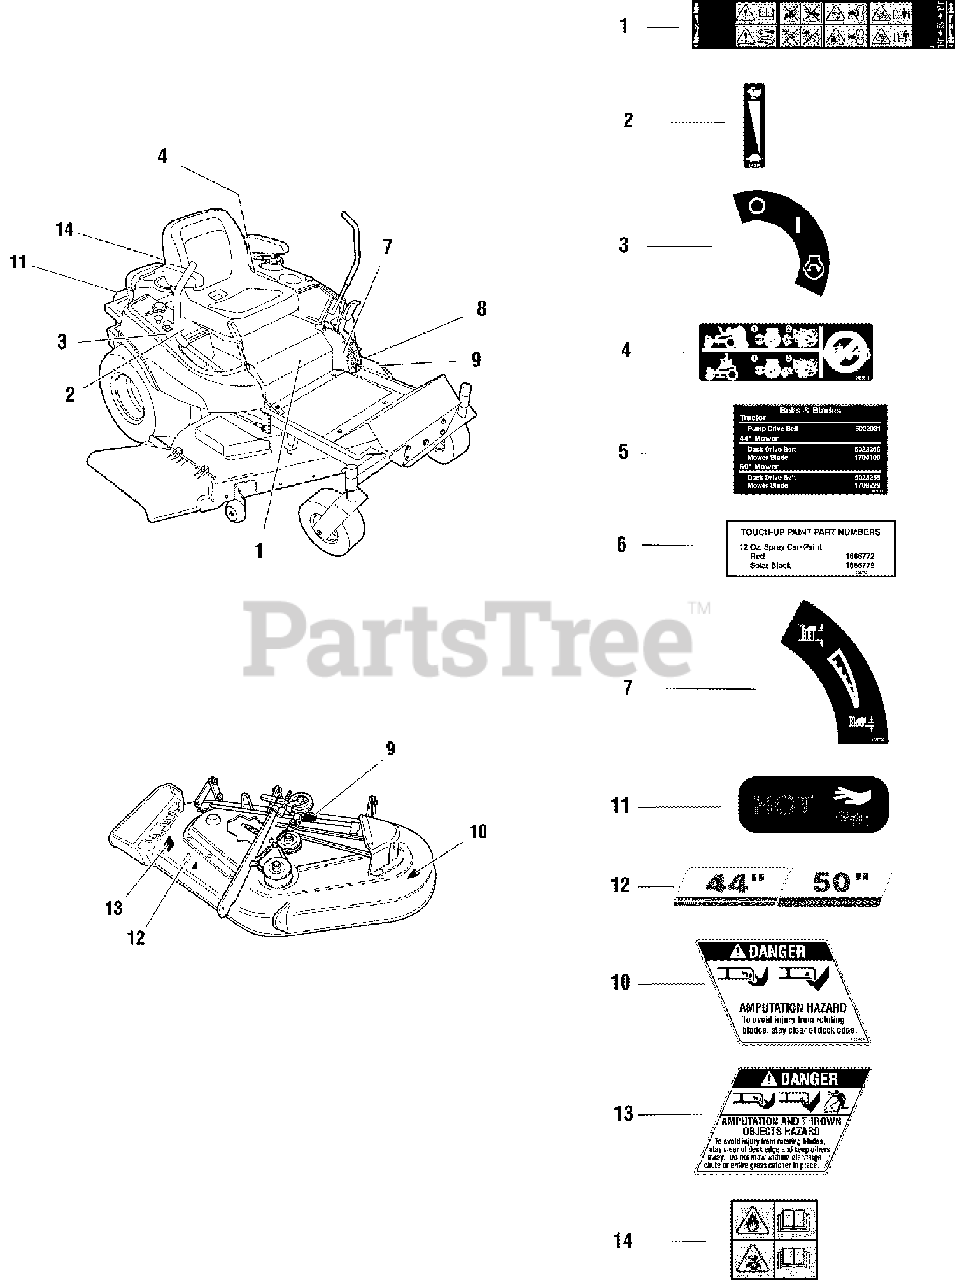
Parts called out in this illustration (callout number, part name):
1	DECAL, MAIN CE
2	DECAL, THROTTLE CONTROL
3	DECAL, IGNITION SWITCH
4	DECAL, CZT HYDRO RELEASE
5	DECAL, BELT & BLADE
6	DECAL-TOUCH UP PAINT
7	DECAL, HEIGHT OF CUT
8	DECAL, US PATENT, ZTR
9	DECAL, ID PLATE
10	DECAL, CE DANGER
11	DECAL, HOT
12	DECAL-44"- SILVER ON BLACK W/STRIPE
12	DECAL-50"- SILVER ON BLACK W/STRIPE
13	DECAL-DANGER ROTATING BLADE SYMBOLS
14	DECAL, DANGER, CE
